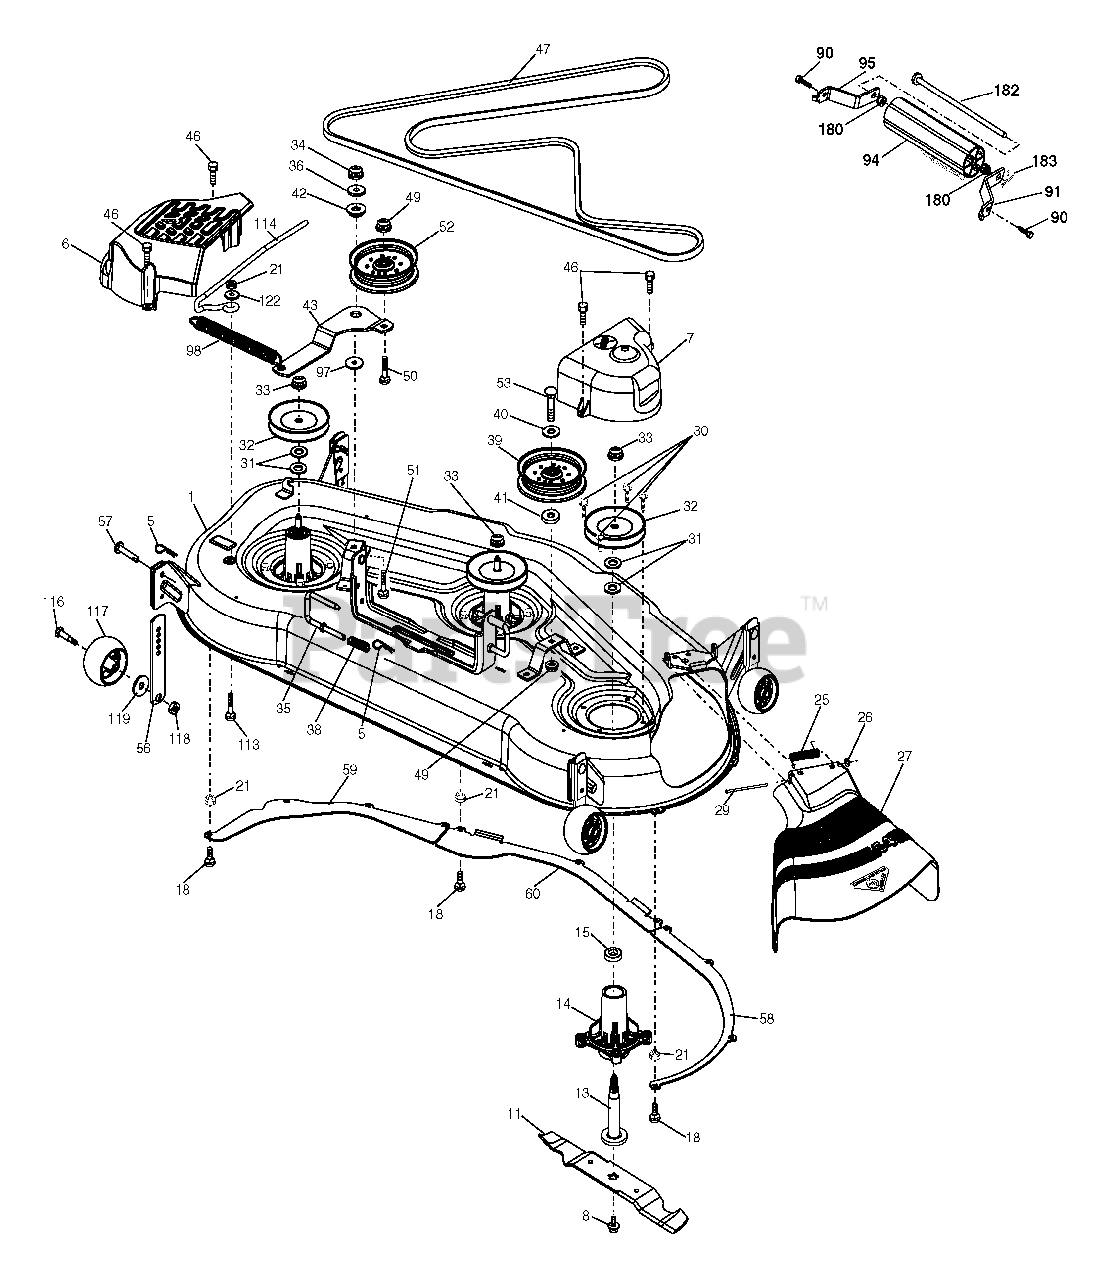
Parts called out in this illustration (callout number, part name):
1	Deck Weldment Mower
5	Retainer Spring
6	Cover Mandrel LH
7	Cover Mandrel RH
8	Bolt 7/16 Asm. Blade
11	Blade, Standard
13	Shaft Asm. w/Lower Bearing
14	Housing, Mandrel
15	Bearing, Ball, Mandrel
17	Bolt, Carriage 5/16-18 x 5/8
21	Nut, Crownlock 5/16-18 unc
25	Spring, Torsion
26	Nut, Push
27	Deflector Shield
29	Rod, Hinge
30	Screw, Thdroll Washer Head
31	Washer, Spacer Mower Vented
32	Pulley, Mandrel
33	Nut, Flg. Top Lock Cntr. 9/16
34	Nut
35	Pin Suspension Rear
38	Spring Compression
39	Pulley, Idler, Stationary
40	Washer 13/32 x 13/16 x 12 Ga.
41	Washer 13/32 x 1-3/8 x 3 Ga.
42	Spacer, Retainer
43	Arm, Idler
46	Screw, Thdroll. 1/4-20 x 5/8
47	V-Belt, Mower, Secondary
49	Nut, Lock Flg. 3/8-16 unc
50	Bolt, Carr. 3/8-16 x 2
51	Bolt
52	Pulley Idler Clutching
53	Bolt Fin Hex 3/8-16 unc x 2-1/4
56	Bar Pnt Adj.
57	Pin Head Rivet
58	Baffle Right
59	Baffle Left
60	Baffle Center
90	Bolt 5/16-18 x 1
91	Bracket Asm N Roller RH
94	Roller Nose 48"
95	Bracket Asm N Roller LH
97	Washer Hardened
98	Spring Clutch Drive
113	Bolt Rdhd Sqnk 5/16-18 x 3/4
114	Rod Tension Relief
116	Bolt, Shoulder
117	Gauge Wheel
118	Nut, Centerlock 3/8-16 unc
119	Washer 3/8 x 7/8 x 14 Ga.
122	Bushing Tension Relief
180	Nut 5/16-18
182	Rod Roller Nose Narrow
183	Retainer Spring
